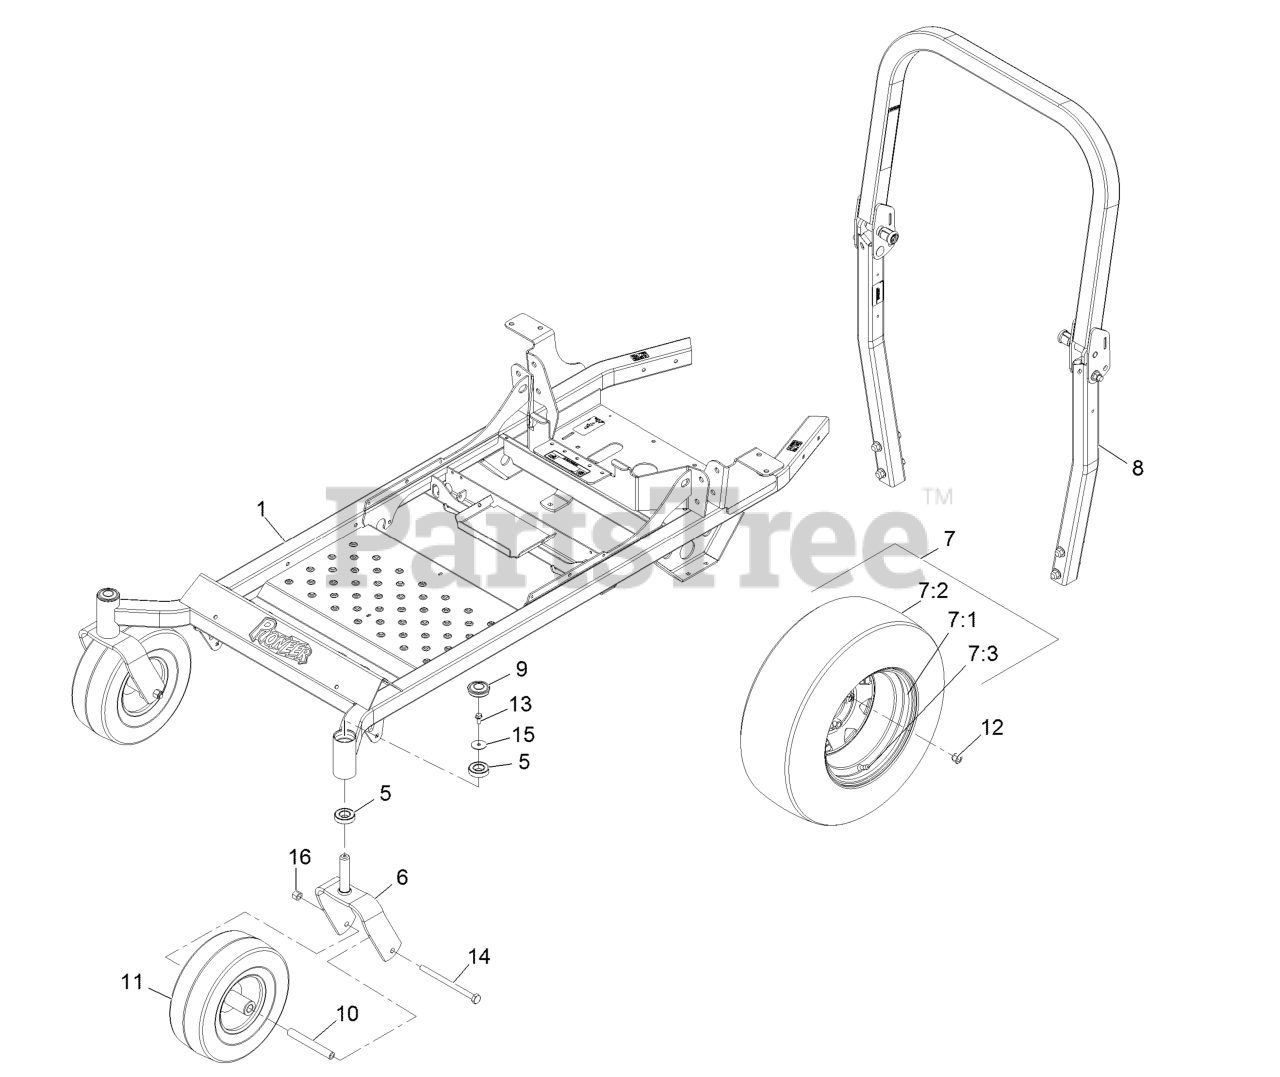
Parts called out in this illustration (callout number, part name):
1	FRAME ASM-48-52
5	BEARING-BALL
6	WLD,CASTER FORK
7	ASM-WHEEL AND TIRE 20 X 8
7:1	WHEEL-10 X 6.00
7:2	TIRE-20 8.00-10
7:3	Stem-Valve
8	ASM-ROPS PIONEER
9	CAP-GREASE
10	SPANNER
11	TIRE AND WHEEL ASM
12	NUT-LUG
13	SCREW-HHF
14	SCREW-HH
15	WASHER-FLAT
16	NUT-LOCK, NI
